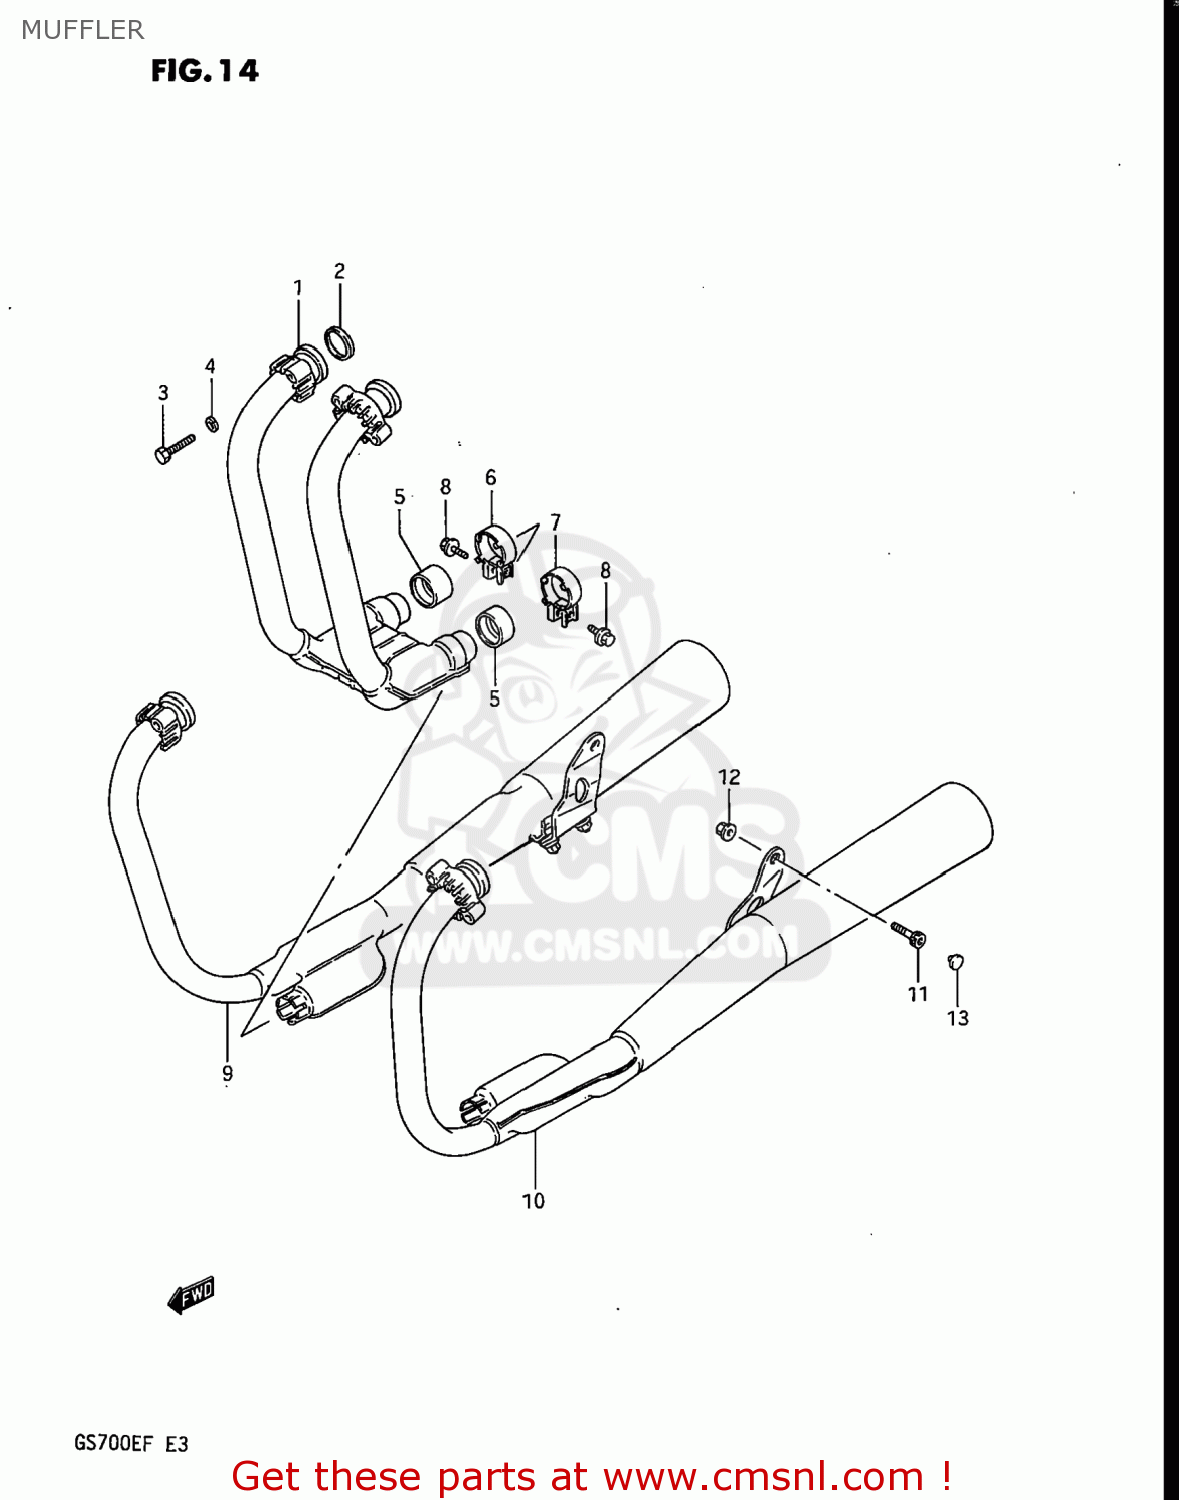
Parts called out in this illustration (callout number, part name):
1	PIPE,EXHAUST
2	GASKET,EXHAUST PIPE (NAS)
3	BOLT 8X40
4	LOCK WASHER
5	CONNECTOR,MUFFLER
6	CLAMP,MUFFLER CONNECTOR
7	CLAMP,MUFFLER CONNECTOR
8	BOLT
9	MUFFLER ASSEMBLY,RIGHT
10	MUFFLER ASSEMBLY,LEFT
11	BOLT 10X25
12	NUT
13	CAP
